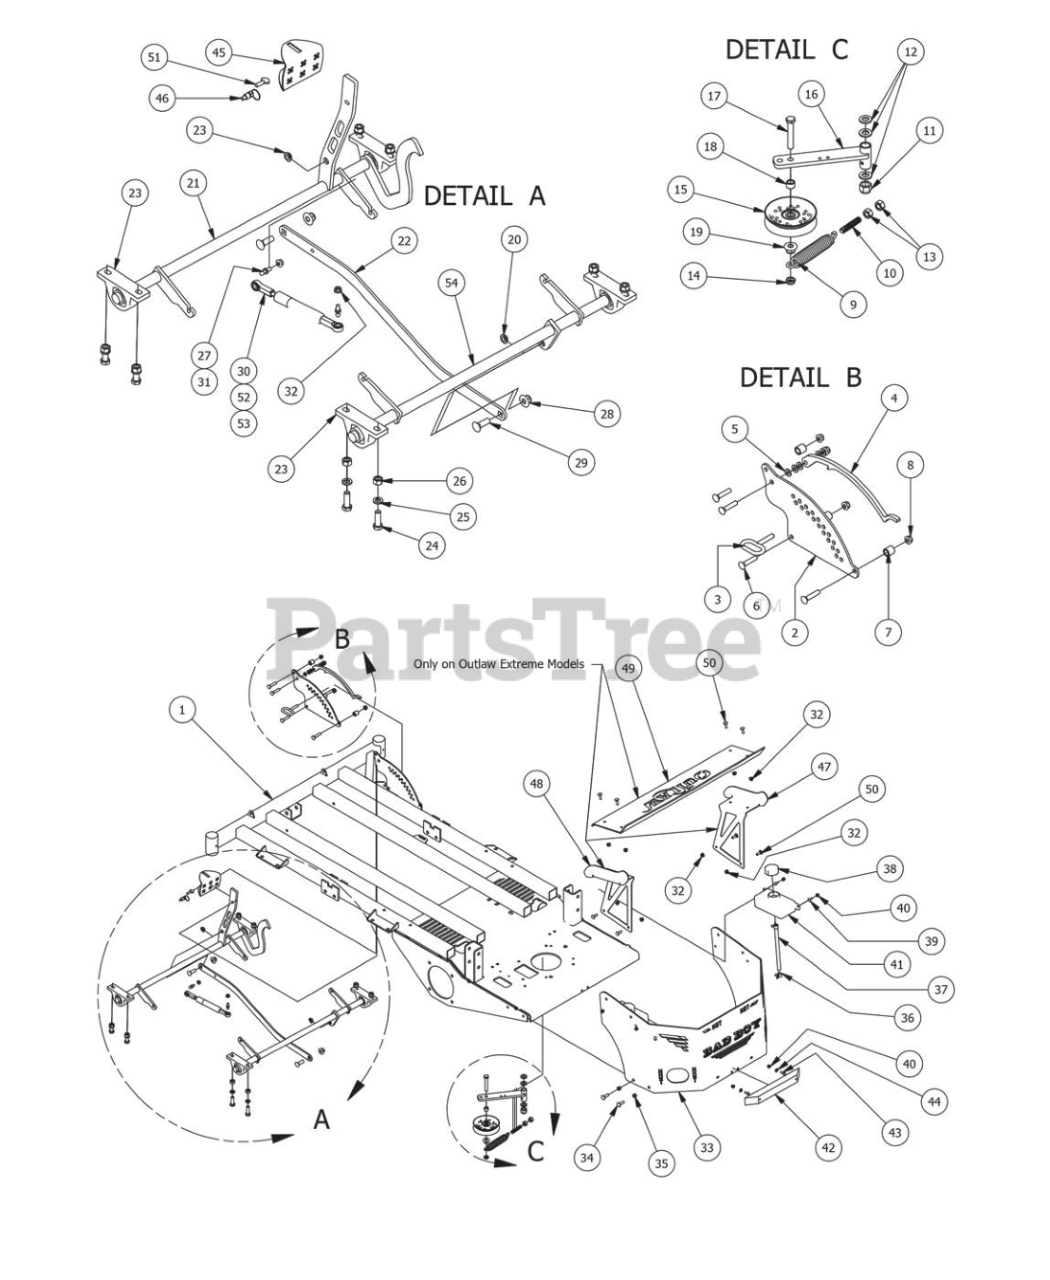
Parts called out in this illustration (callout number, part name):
1	Outlaw Frame
2	Outlaw Height Indicator Plate (Outer)
3	Deck height lever pin
4	Outlaw Deck Lever Lock
5	.390 x .750 x .062 Nylon Washer
6	3/8 x 1 3/4 Carriage Bolt
7	3/4 OD x 1/2 ID x 3\4 Length
8	3/8" Nylock Flange Nut
9	Pump Idler Spring
10	All Thread-pump Idler Tensioner
11	5/8 Std NC Nylock Nut
12	.635 ID Plastic Washer
13	1/2" Hex Nut
14	1/2" Nylcock Nut (1/2 Jam)
15	4-3/4 Idler Pulley
16	Deck Idler
17	1/2-13 x GR 5 Hex Bolt Zinc
18	1/2 x 1/2 Spacer
19	1/2-13 Nylon Flange Nut-Orange
20	Bushing- SF-1620-4
21	Outlaw Front Actuator Bar Assembly
22	Outlaw Deck Linkage Rod
23	Pillow block Bearing
24	1/2" 1 1/2" Hex Bolt
25	1/2" Lock Washer
26	1/2" Hex Nut
27	10mm Damper Ball Stud-Steering Only on 54" & 61" Decks
28	1/2-13 Nylon Flange Nut-Orange
29	1/2 x 1-1/2 Carriage Bolt
30	200 lb Gas Spring- 54" Deck outlaw
31	13mm Damper Ball Stud for 72" Deck only
32	5/16-18 Hex Flange Nuts
33	Outlaw Rear Plate
34	3/8" x 1 1/4" Carriage Bolt
35	3/8 Nylock Nut
36	5/8 Wire Clamp-Outlaw Only
37	5/8 Braided Hose
38	Hydraulic Tank Cap
39	1/4" x 3/4" Carriage Bolt
40	1/4-20 Nylon Insert flange Nut
41	Expansion Tank Outlaw
42	14" Rubber Bumper
43	1/4-20 x 1-1/4 GR 5 Hex Bolt
44	1/4" Flat Washer
45	Outlaw Deck Lift Pedal
47	Spoiler Side Support Right
48	Spoiler Side Support Left
49	Outlaw Spoiler Plate
50	5/16" x 1" Carriage Bolt
51	5/16-18 x1 Thumb Screw Zinc
52	300 lb Gas Spring -72" Deck Outlaw
53	250 lb Gas Spring -61" Deck outlaw
54	Outlaw Rear Actuator Bar Assy
